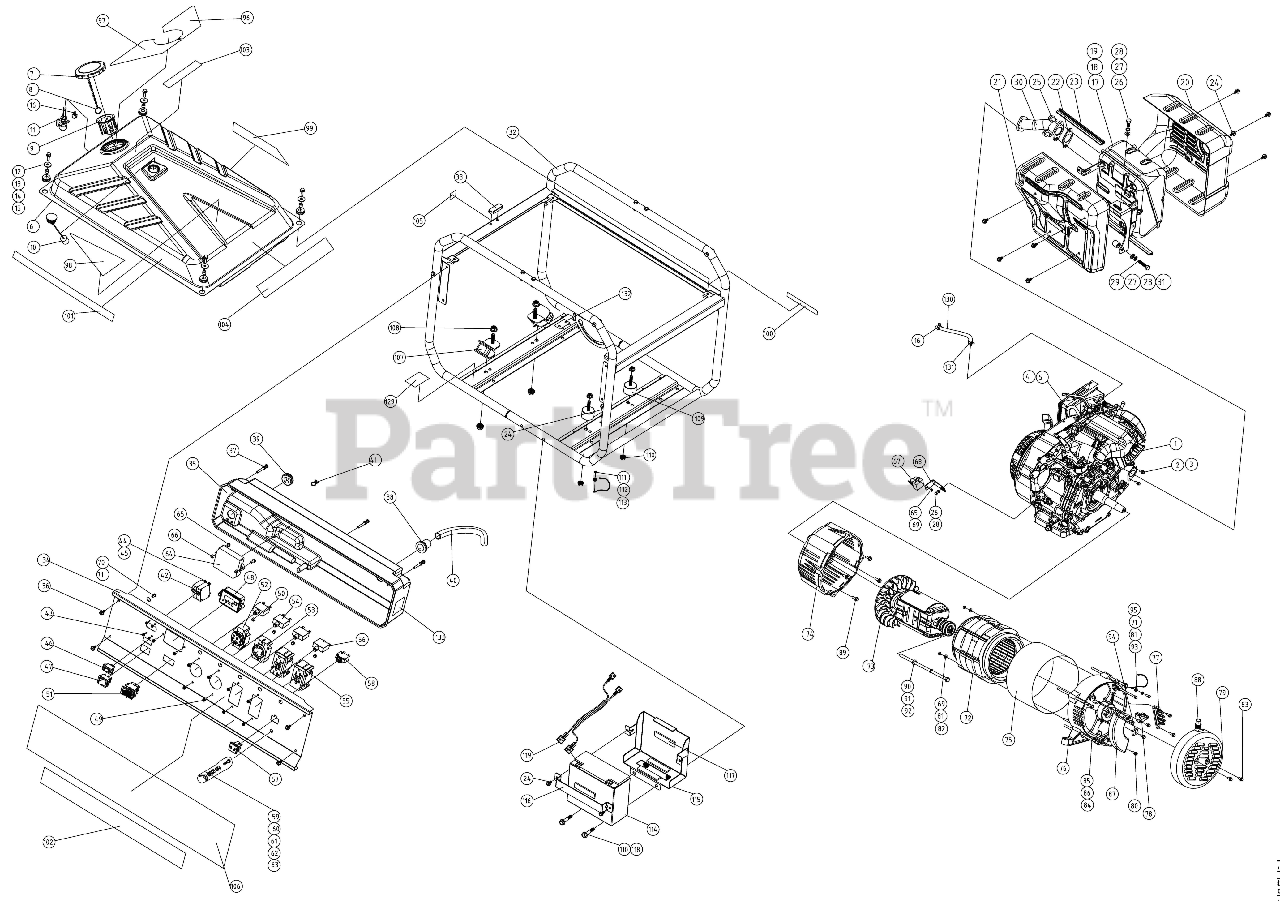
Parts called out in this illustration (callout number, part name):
1	CH440 E3 KPP
2	GASKET, EXHAUST PIPE
3	NUT USE 25 086 240-S
4	FUEL HOSE, LOW PERMEATION
5	CLAMP, FUEL LINE 1 USE 14 237 01-S
6	TANK, FUEL
7	CAP ASSEMBLY - FUEL TANK (EPA)
8	RETAINER, TANK CAP PULL RING
9	FILTER , FUEL TANK
10	GUAGE, FUEL LEVEL ASSEMBLY
11	VALVE,FUEL SHUT OFF
12	SCREW, BOLT GB 5787-M6X20
13	MOUNT, FLAT GASKET GB/T 5287-6
14	SPACER, FUEL TANK BUSHING
15	SPACER, INNER RING
16	CLAMP, FUEL LINE 6
20	COVER, MUFFLER FRONT
21	COVER, MUFFLER BACK
23	MOUNT, RUBBER GASKET
24	SCREW, BOLT M6X12
25	SCREW, BOLT M8X22
26	SCREW, BOLT M8X20
27	WASHER, FLAT GASKET 8
28	WASHER, SPRING 8
29	SCREW, BOLT L35
30	MUFFLER PIPE
31	SPACER, MUFFLER BUSHING
32	FRAME ASSEMBLY
33	DAMPER, HANDLE DAMPING PAD
34	PANEL (PRO5.2E)
35	ELECTRIC BOX
36	SCREW, BOLT GB5789-M6X12
37	SCREW M5X45
38	GROMMET, POWER CORD SHEATH
39	GROMMET 16MM
40	PIPE, CORRUGATED
41	STRAP, CABLE TIES 3.2X120 (WHITE)
42	BREAKER, CIRCUIT 18.5A (PRO 5.2E)
43	SCREW, M3X6
44	SCREW GB818-M4X8
45	WASHER, SPRING GB93-4
48	DIGITAL DISPLAY METER
49	SCREW M4X12
52	L 14-30 SOCKET
53	RECEPTACLE, NEMA L5-30R SOCKET
54	BREAKER, CIRCUIT 30A
55	RECEPTACLE, GFCI 20A/125V NEMA 5-20OR
56	BREAKER, CIRCUIT 20A
57	RECEPTACLE, DC SOCKET 12V8.3A
58	BREAKER, CIRCUIT DC 8A
59	SCREW, BOLT M6X25
61	WASHER, PLATE GASKET 6
62	WASHER, SPRING GASKET 6
64	MODULD, IDLE CONTROL
65	SCREW M5X16-GB818
67	RECTIFIER, BLOCK (PRO5.2E)
68	BRACKET, STATIONARY BARRIER
70	SCREW M5X12
71	WASHER, SPRING GB 93-5
72	STATOR ASSEMBLY
73	ROTOR ASSEMBLY (PRO5.2E)
76	CAP, BACK COVER
77	BOARD ASSEMBLY, PATCH
78	BRUSH, CARBON ASSEMBLY
79	FAN COVER
80	SCREW, BOLT GB 5787-M5X16
81	WASHER, PLATE GT/T 95
82	SCREW, BOLT M5X205
83	SCREW, BOLT M5X10
84	SCREW BOLT M6X180
85	WASHER, PLATE GASKET 6
86	WASHER, SPECIAL SPRING 6
87	RECTIFIER AVR (PRO5.5E)
88	SLEEVE, MOTOR RUBBER SHEATH
89	SCREW BOLT 3/8-16X27MM
90	BOLT 5/16-24X222MM
92	WASHER, SPRING
93	BOLT GB/T 5783-M5X10
94	RETAINER, 12V DC CHARGE BRIDGE
95	WIRE, 10GA WHITE
96	DECAL, TANK BRAND, LEFT
97	DECAL, TANK REMIND, RIGHT
98	DECAL, TANK, BRAND POWER
99	DECAL, TANK BRAND, LEFT
100	SAFETY DECAL
101	CPSC DECAL_5.2
102	DECAL, OPERATE
103	DECAL, OSHA
104	DECAL, GENERATOR_WARNING
105	FUEL SWITCH DECAL
106	DECAL, PLATE PRO 5.2E-CSA
107	MOUNT, ENGINE ISO
109	MOUNT, RUBBER FOOT
111	GROUND WIRE
112	SPACER, FLOWER SHAPED GASKET
114	KIT, BATTERY RACK 12V18AH
115	SUPPORT, BATTERY MOUNTING ASSEMBLY
116	BRACKET, BATTERY
117	DAMPER - DAMPING STRIP
118	BOLT M8X40 GB 5789
119	HARNESS ASSEMBLY, WIRING
128	STRAP, CABLE TIES 7.7X150 8
129	DECAL, S/N
130	FUEL PIPE
131	PIPE CLAMP
132	DECAL, PRO5.E PERFORMANCE
133	(CSA) EMC DECAL
